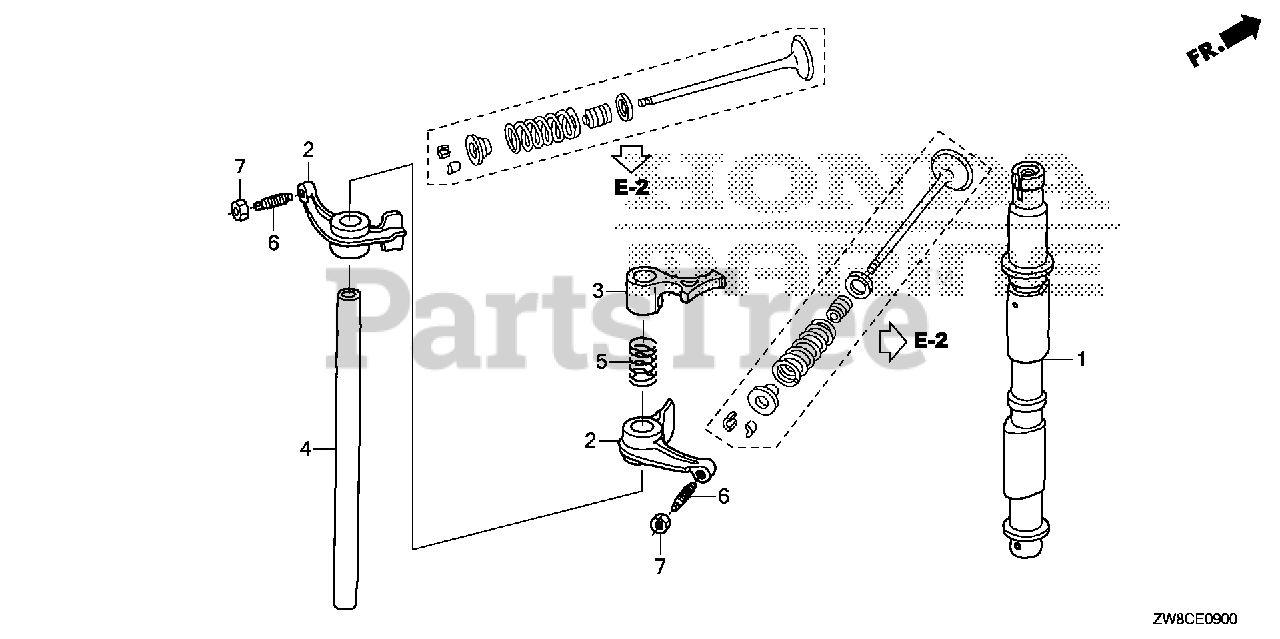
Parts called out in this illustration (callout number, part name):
2	ARM, VALVE ROCKER
3	ARM, FUEL PUMP ROCKER
4	SHAFT, ROCKER ARM
5	SPRING, ROCKER ARM
6	SCREW, TAPPET ADJUSTING
7	NUT, TAPPET ADJUSTING
